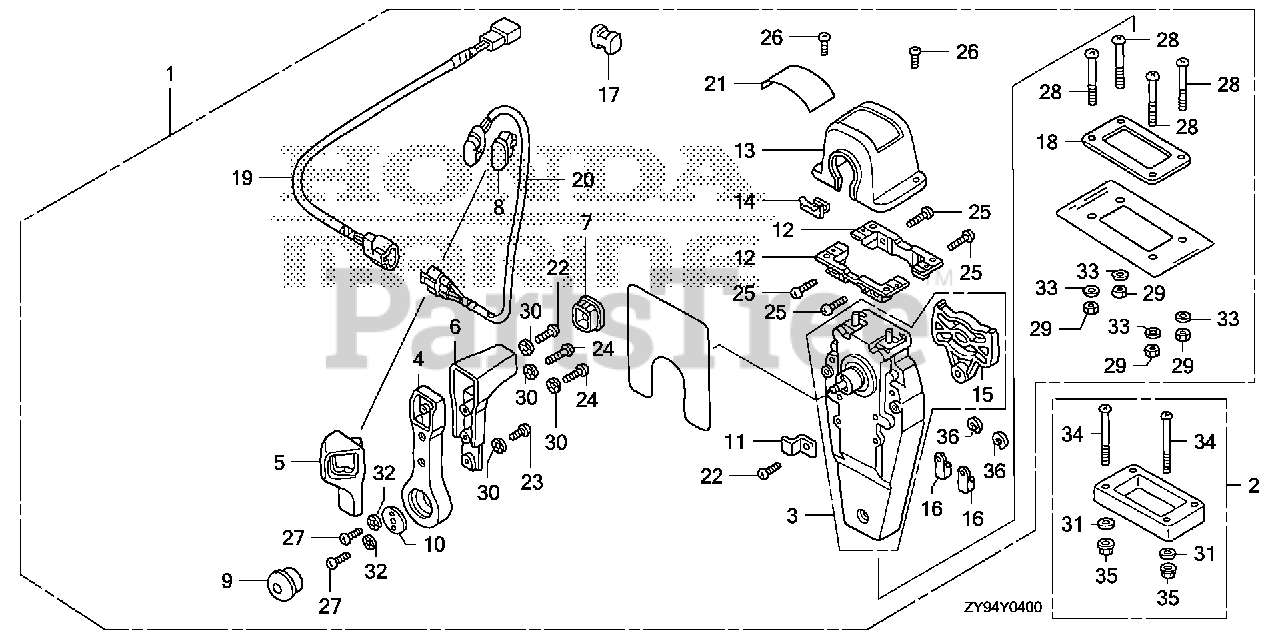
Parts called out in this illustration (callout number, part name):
1	BOX KIT, REMOTE CONTROL (TOP MOUNT SINGLE)(R)
2	SPACER KIT, REMOTE CONTROL BOX (TOP MOUNT SINGLE)
3	HOUSING ASSY., L. (INNER) (TOP MOUNT)
4	HANDLE, REMOTE CONTROL
5	COVER, L. GRIP
6	GRIP, REMOTE CONTROL HANDLE
7	CAP, GRIP
8	CAP, SWITCH
9	BUTTON, THROTTLE
10	PLATE, HANDLE
11	PLATE, CABLE CLAMP
12	BRACKET, REMOTE CONTROL HOUSING
13	HOUSING, REMOTE CONTROL BOX
14	HOUSING, LEAD
15	PLATE, DWELL
16	TERMINAL, CABLE
17	SPACER, CABLE CLAMP
18	GASKET, SINGLE
19	SUB-HARNESS ASSY., POWER TRIM-TILT (A)
20	SWITCH ASSY., POWER TRIM-TILT (A)
21	MARK, REMOTE CONTROL (SINGLE)
22	SCREW, PAN (5X16)
23	SCREW, PAN (5X10)
24	SCREW, PAN (5X20)
25	SCREW, PAN (5X18)
26	SCREW, PAN (4X10)
27	SCREW, PAN (6X18)
28	SCREW, PAN (5X40)
29	NUT, HEX. (5MM)
30	WASHER, LOCK (5MM)
31	WASHER, PLAIN (5MM)
32	WASHER, LOCK (6MM)
33	WASHER, PLAIN (5MM)
34	SCREW, PAN (5X65)
35	NUT, HEX. (5MM)
36	E-RING (6MM)
